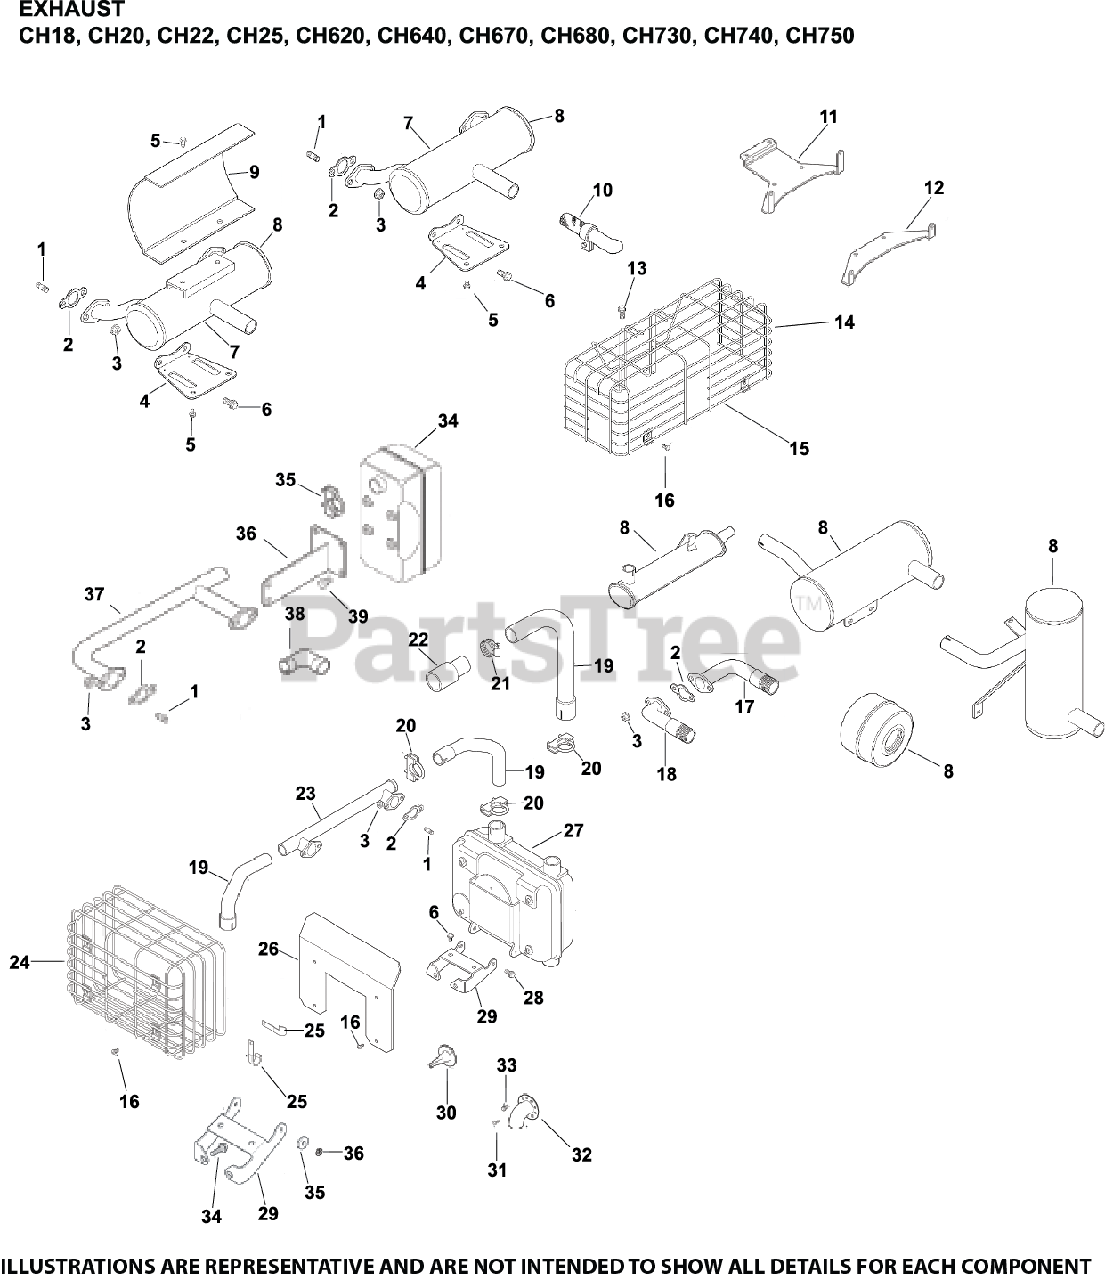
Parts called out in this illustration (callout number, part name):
1	STUD, EXHAUST-USE 25 072 24-S
2	GASKET, EXHAUST
3	NUT, FLG M8X1.25
4	BRACKET, MUFFLER
5	SCREW, FLG M6X1.0X12
6	SCREW, FLG M8X1.25X20
7	KIT, MUFFLER
8	MUFFLER, CANISTER-STRT OUTLET - USE 24 068 129-S
12	BRACKET, MUFFLER GUARD SP
13	SCREW,FLG THD FRM M5X0.8X16-(#25086398S)
14	GUARD, MUFFLER
15	KIT, MUFFLER GUARD
